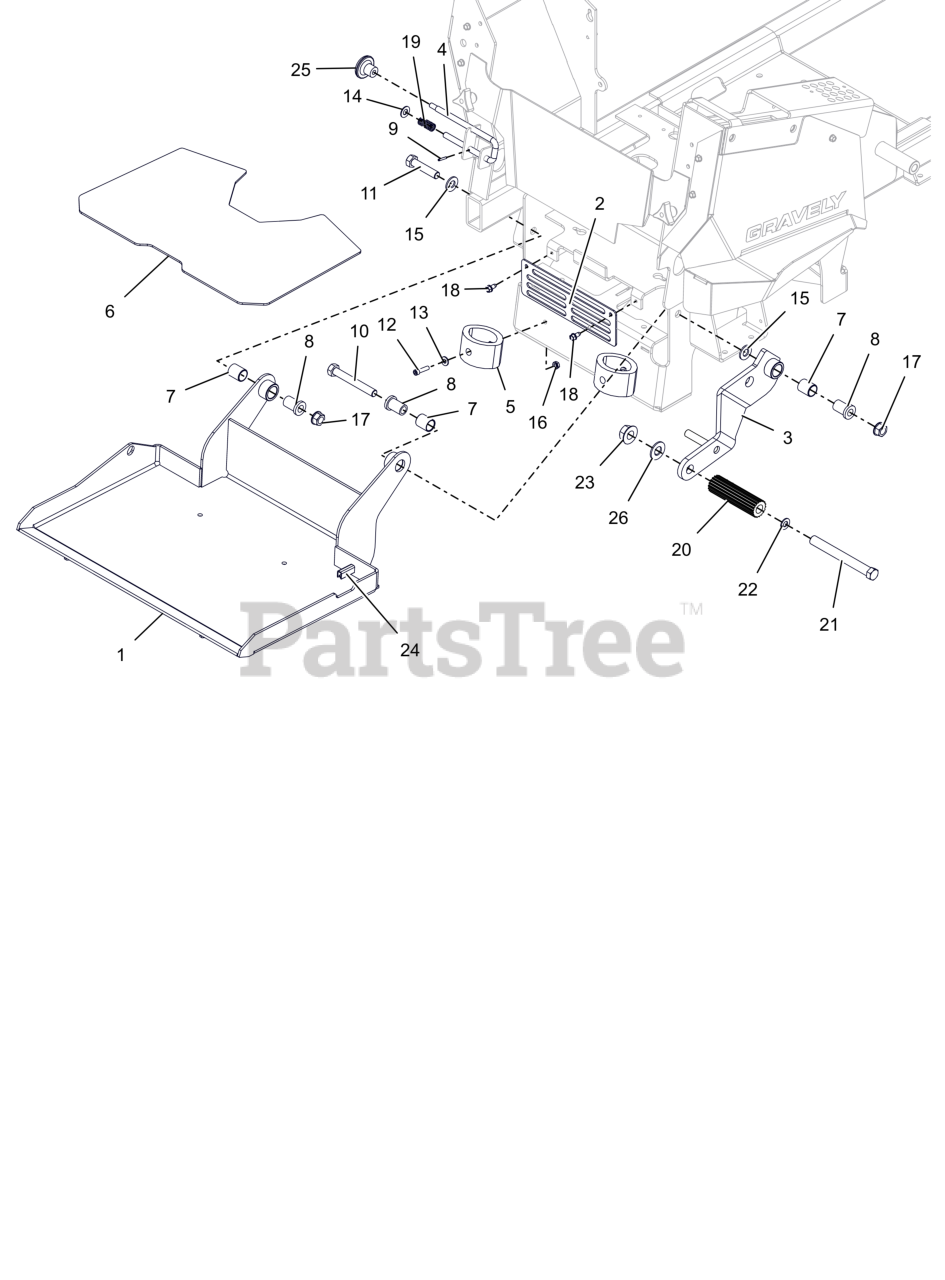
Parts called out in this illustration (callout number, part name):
1	PLATFORM, 32-36" OPERATOR (BLACK)
2	GUARD, FOOT (RED)
3	WLDMT, DECK LIFT FOOT ASSIST (BLACK)
4	PIN, PLATFORM LOCK
5	BUMPER, PLATFORM
6	TAPE, OPERATOR PLATFORM GRIP
7	BRG, .750 X .875 X 1.000
8	BSHG-FLG .515X.746X1.290X1.000
9	PIN-ROLL .125X.75
10	BLT,HEX .50-13X3.75 G5 ZCC
11	BLT, HEX .50-13X2.25 G5 ZCC
12	SCR, SKH .25-20X1.00
13	WSHR,FLT .281X.625X.065 ZCC
14	WSHR-FL-STL 0.406X0.812X0.055 HRD
15	WSHR,FLT .531X1.062X.095 ZCC
16	NUT-KEPS .250-20 ZCC
17	NUT-LK-CTR-FLG .500-13 GG ZCC
18	SCR-TAP .25-20X.50 HWH ZCC
19	SPRING, COMPRESSION
20	ROD, FOOT PEDAL (BLACK)
21	BLT, HEX .62-11X5.50 G5 FBP
22	WSHR,FLT .406X.812X.065 ZCC
23	NUT,FLG-TOP LK .625-11 FBP
24	STRIP, COWL
25	KNOB, PUSH-PULL .312-18
26	WSHRFLT 5/8SAE CARBHARD FBP
